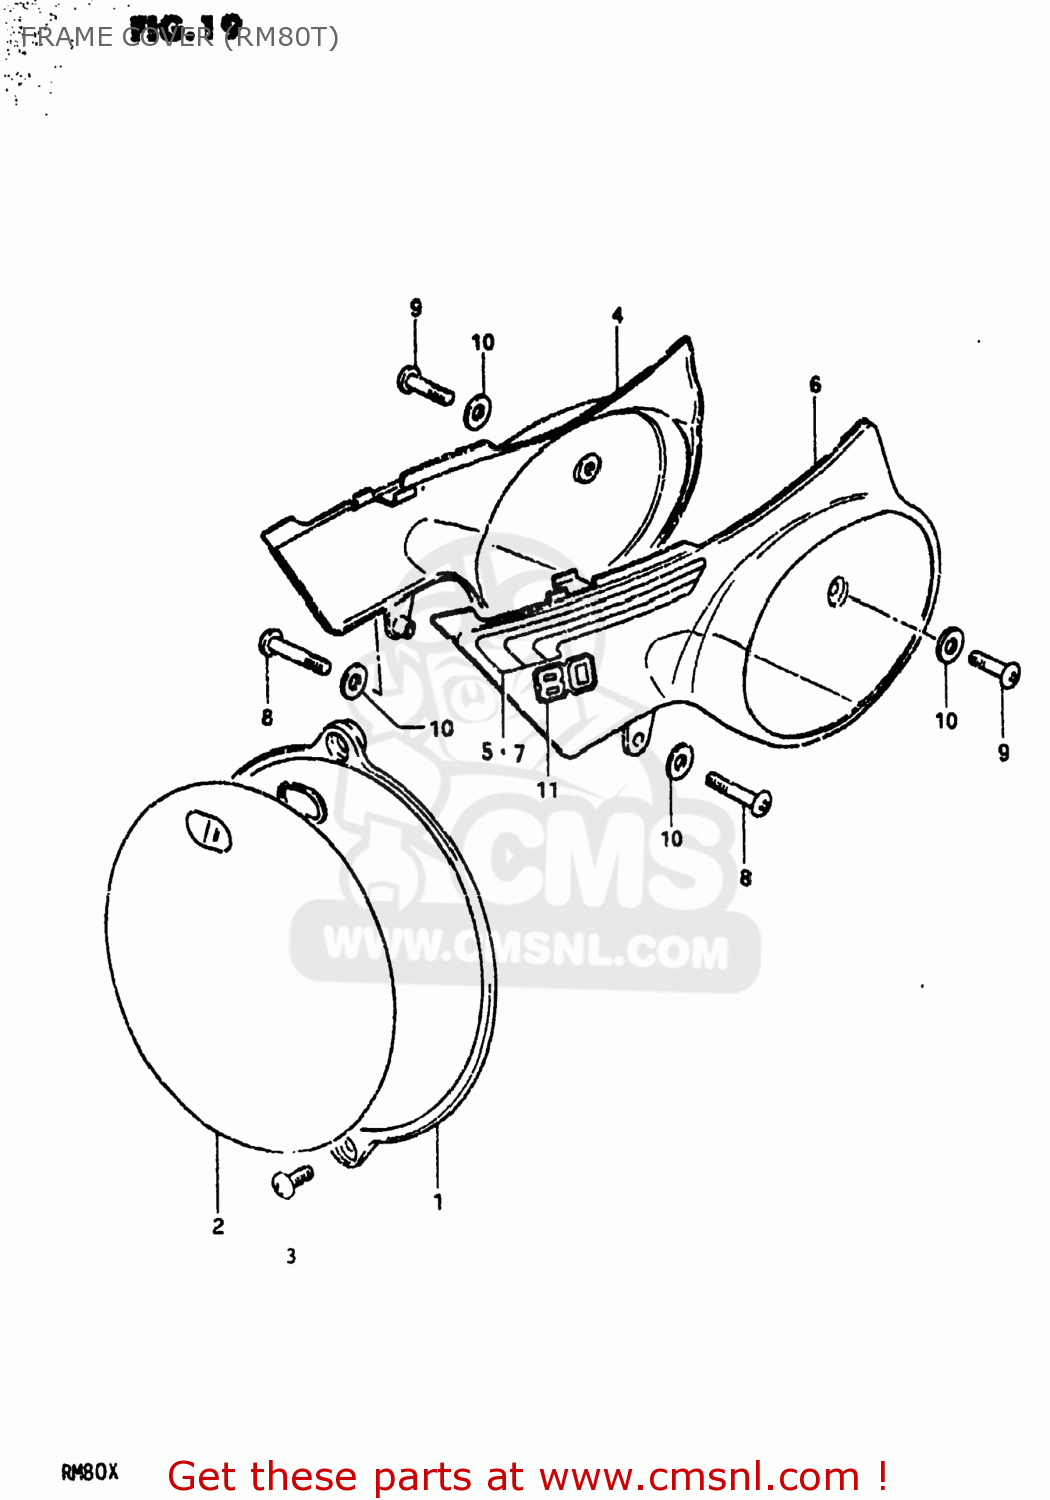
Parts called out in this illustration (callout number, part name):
1	PLATE,NUMBER,FRONT
2	EMBLEM,FRONT NUMBER PLATE
3	SCREW
4	COVER,FRAME,R(YELLOW)
5	TAPE,FRAME COVER,RIGHT STRIPE
6	COVER,FRAME,LEFT
7	TAPE,FRAME COVER
8	SCREW, NO. 1
9	SCREW
10	WASHER
11	EMBLEM
